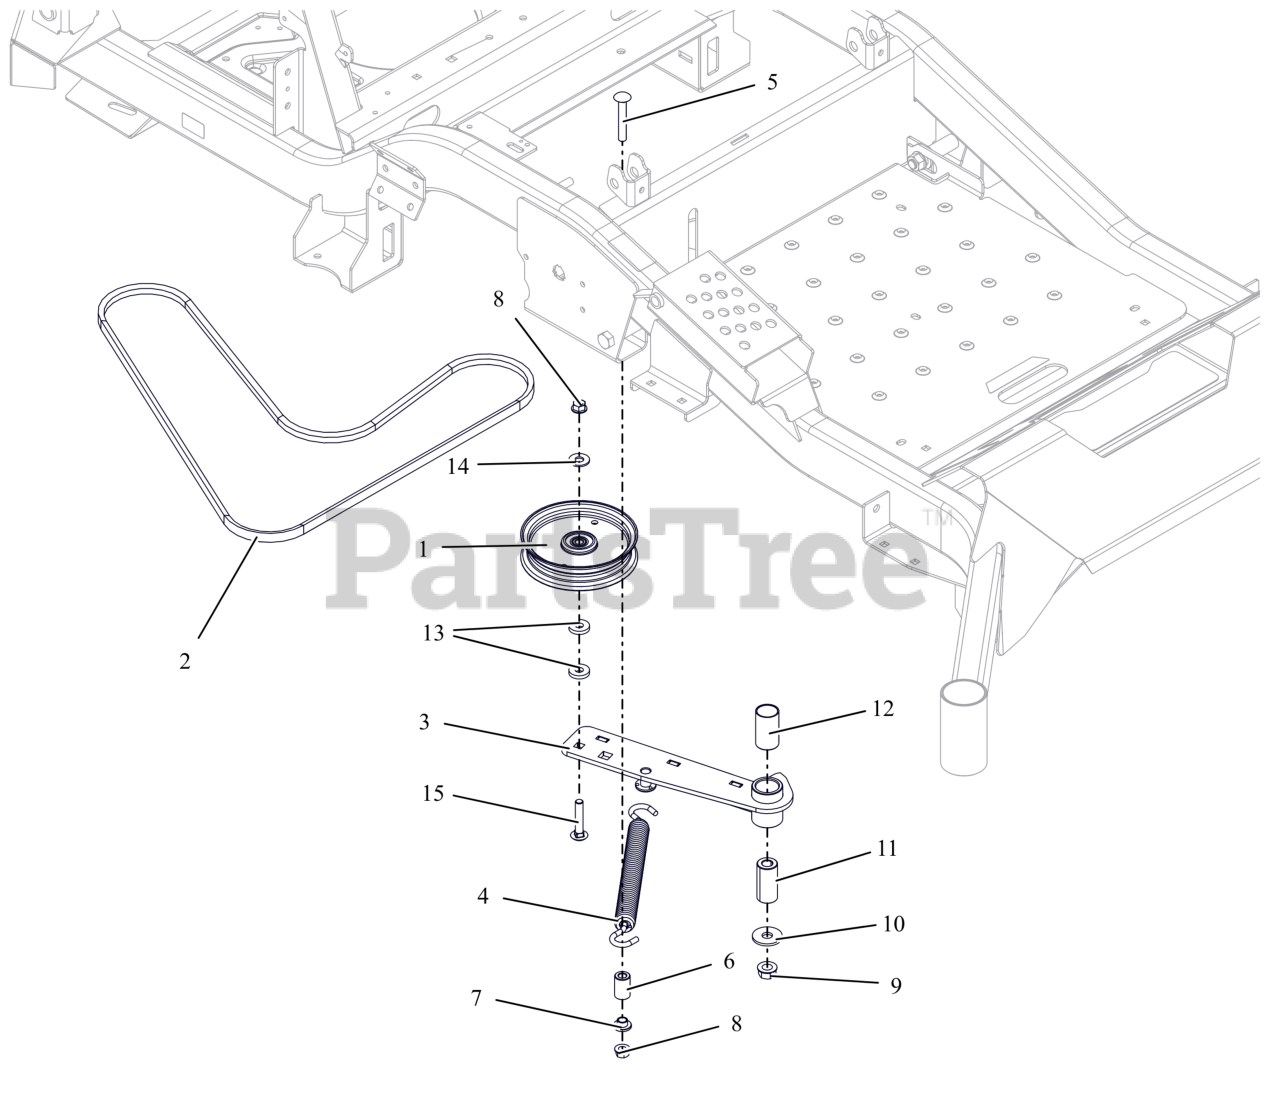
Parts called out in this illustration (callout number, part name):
1	IDLER- FLAT - 5.00" X .75"
2	V-BELT, 4L-WRAPPED
3	WLDMT, HYDRO DRIVE IDLER ARM (BLACK)
4	SPRING, EXTENSION
5	BLT, RHSSN.38-16X2.50 G5 ZCC
6	BUSHING, SLV .380X.750X1.190
7	BSHG-FLG .385X.500X.875X.406
8	NUT-LK-TOP-FLG .38-16 ZC120
9	NUT-LK-TOP-FLG .500-13 GF ZCC
10	WSHR-FL-STL.511X1.44X.125ZC120
11	BSHG, SPCR .502X.997X2.03 PM
12	BSHG, 1.00X1.125X1.937
13	WSHR, FLT .406X1.00X.188 ZCC
14	WSHR,FLT .438X1.00X.083 ZCC
15	BLT, RHSN .38-16X2.00 G5 ZCC
